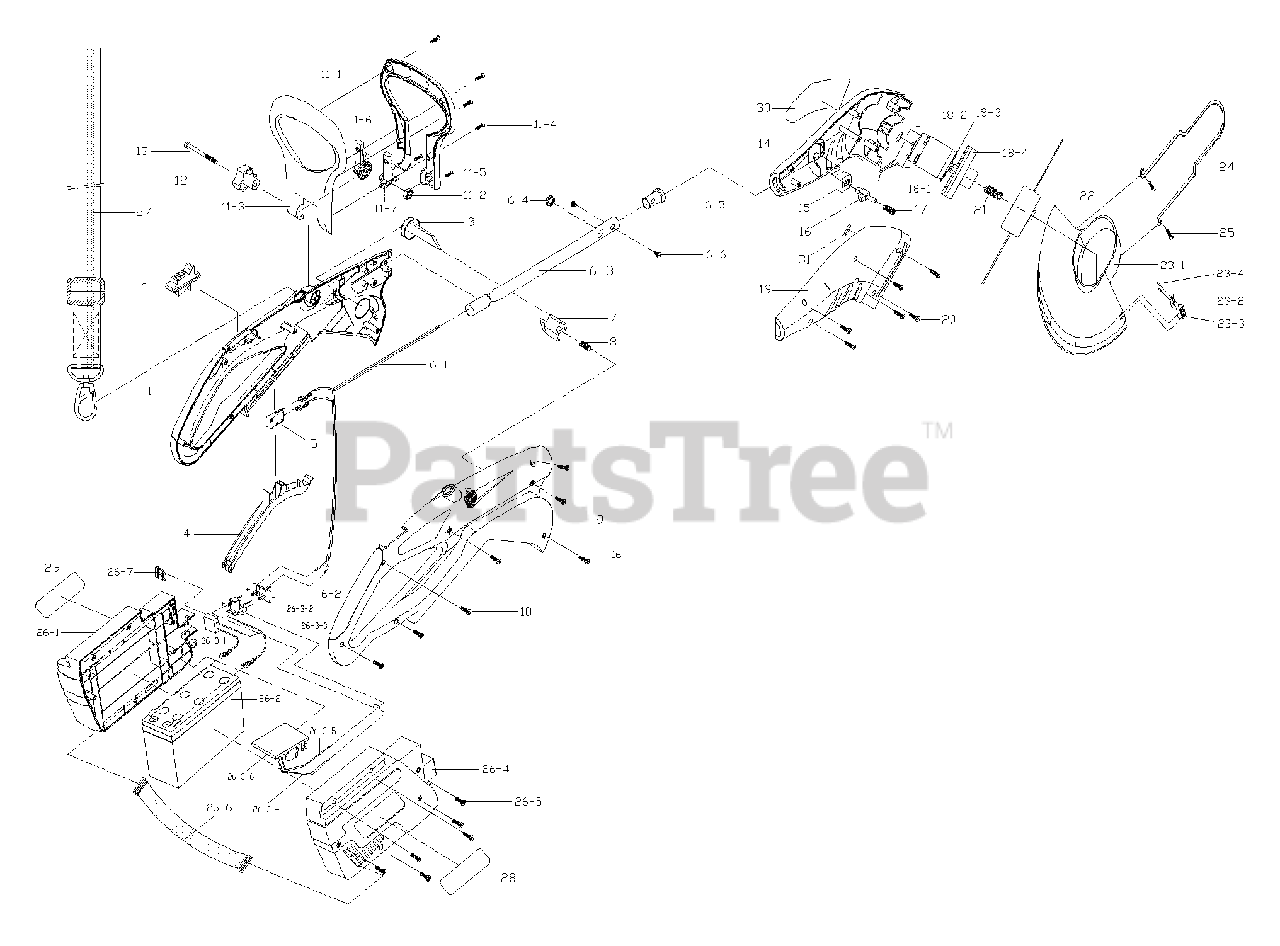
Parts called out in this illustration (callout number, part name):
1	HOUSING (L)
2	PUSH BUTTON
3	BUTTON RELEASE
6	TUBE ASS'Y
7	BATTERY LOCK
9	HOUSING (R)
11	HANDLE ASS'Y
14	MOTOR HOUSING (L)
15	LOCK RELEASE
18	MOTOR ASS'Y
19	MOTOR HOUSING (R)
22	SPOOL ASS'Y
23	GUARD ASS'Y
25	SCREW
26	BATTERY ASS'Y
28	NAME PLSTE
29	NAME PLSTE
30	RATING LABEL
